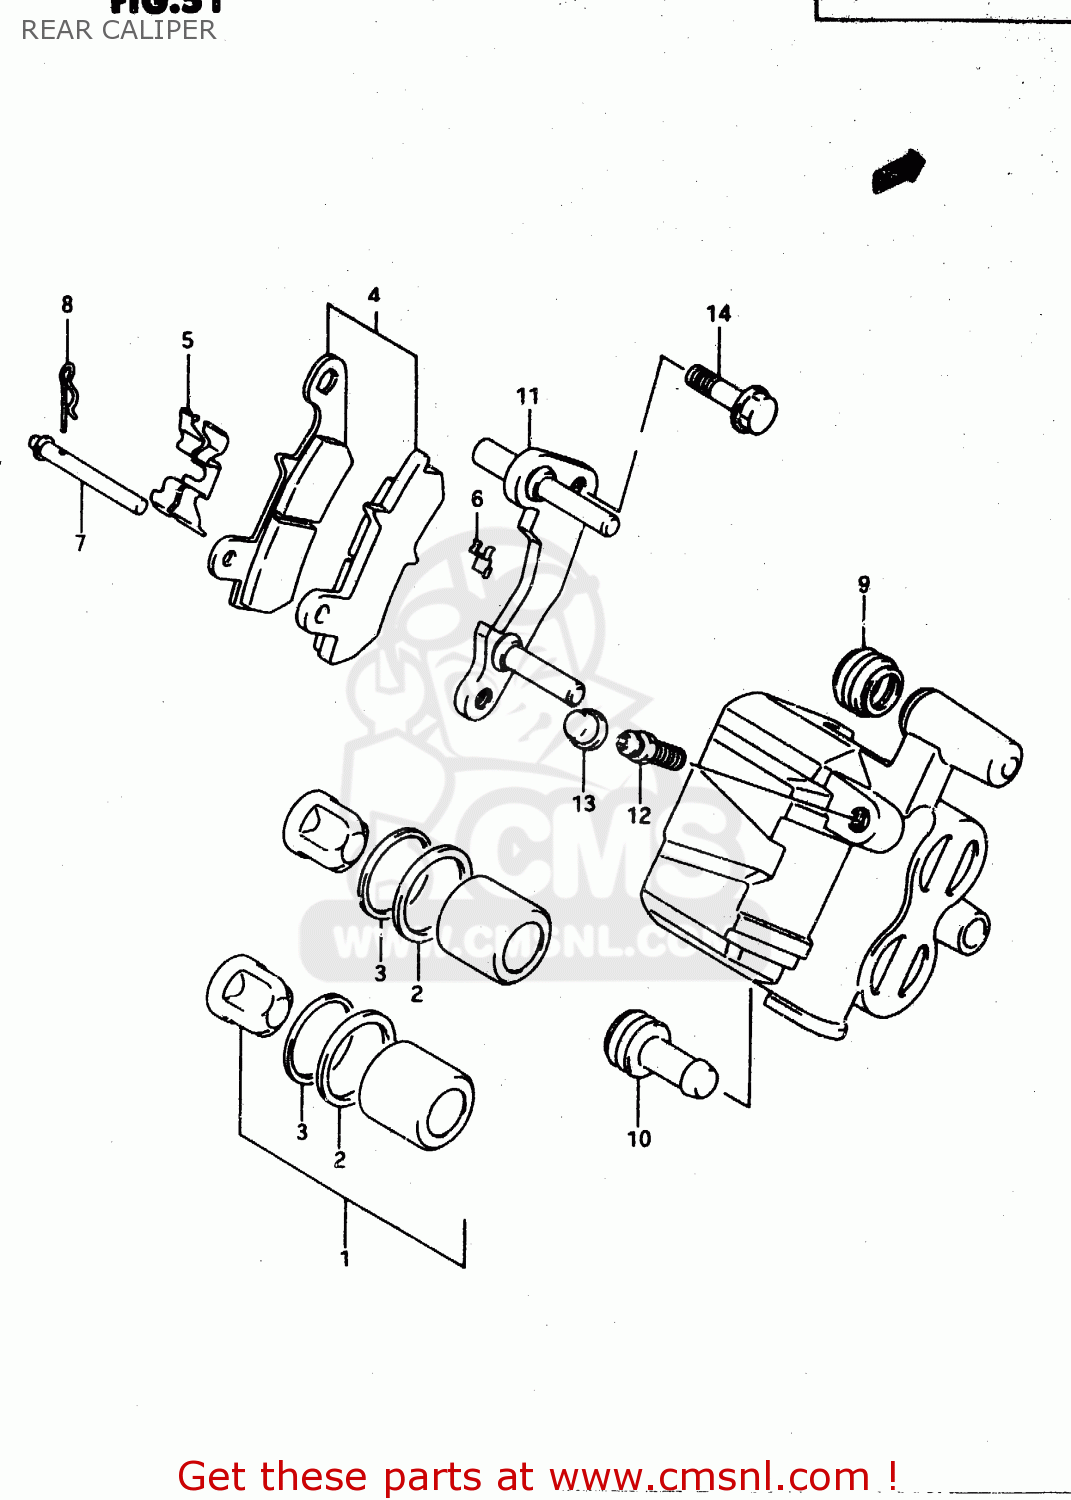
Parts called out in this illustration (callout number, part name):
1	BRAKE PISTON SET
2	SEAL,PISTON
3	SEAL,WIPER
4	PAD SET (NAS)
5	SPRING,PAD
6	GUIDE,PAD
7	PIN,PAD
8	CLIP,PAD PIN
9	BOOT,AXLE
10	INSULATOR,AXLE
11	CARRIER
12	BLEEDER
13	CAP,BLEEDER PLUG
14	BOLT(8X22)
